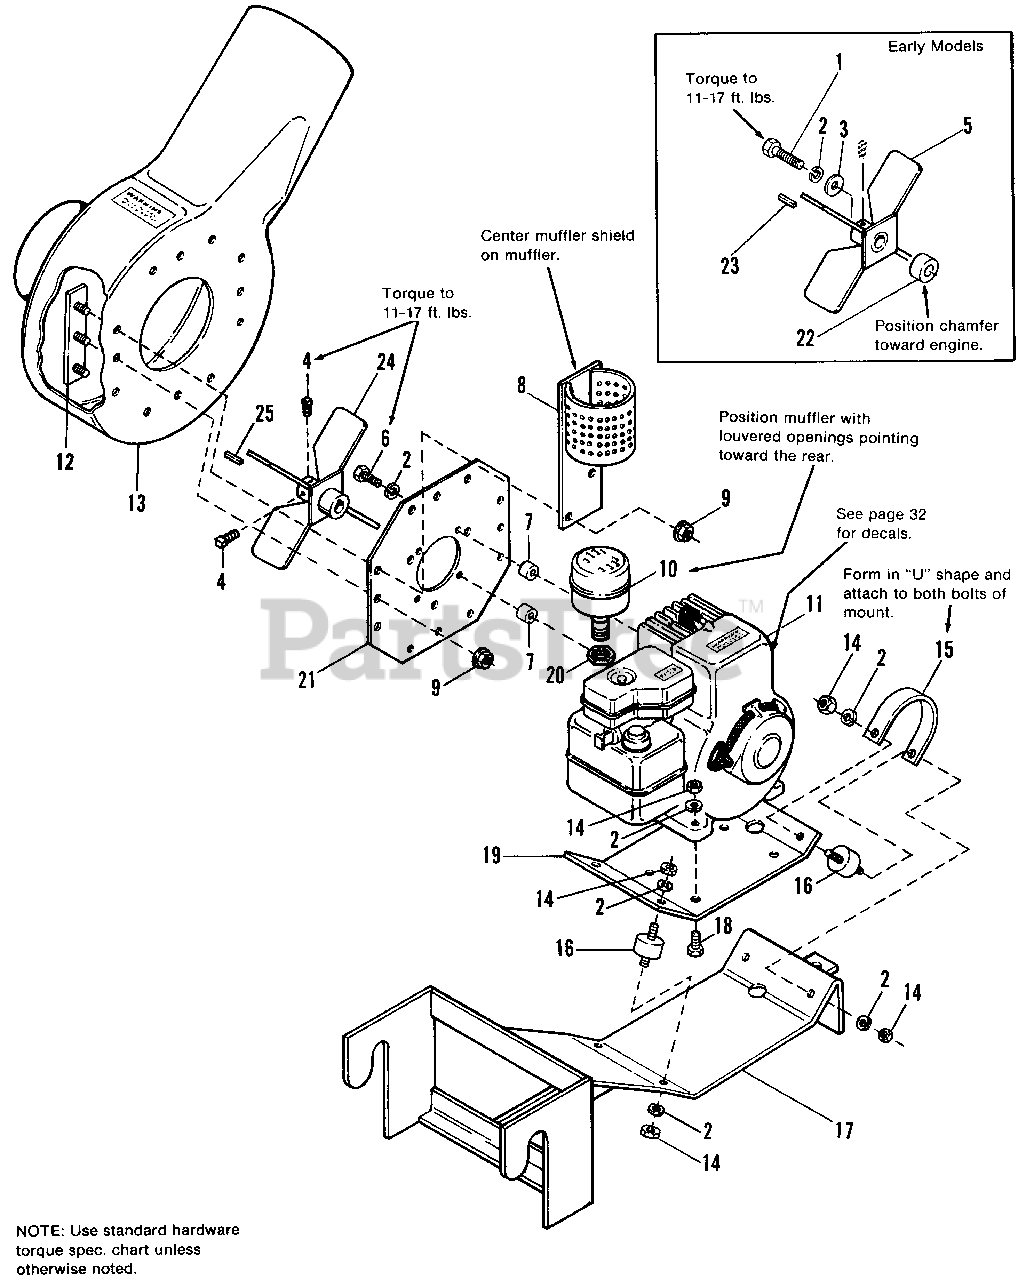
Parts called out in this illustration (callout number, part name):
1	CAPSCREW, Hex Hd., 5/16-24 x 1/2
2	LOCKWASHER, 5/16 (Qty.17 used before s/n 2890)
3	WASHER
4	SETSCREW, 5/16-18 x 1/2
5	FAN ASSY.
6	CAPSCREW, Hex Hd., 5/16-24 x 1-1/4
8	SHIELD ASSY., Muffler
9	LOCKNUT, Hex, Flange, 5/16-18
11	ENGINE, Briggs & Stratton, 4 HP
12	BAR ASSY.
14	NUT, Hex, Full, 5/16-18
15	STRAP, Ground
17	FRAME ASSY.
18	CAPSCREW, Hex Hd., 5/16-18 x 1-1/2
19	PLATE, Engine
20	LOCKNUT, 1/2
21	PLATE, Housing Support
22	SPACER
23	KEY, 3/16 x 3/16 x 1
24	FAN ASSY., 3/16 x 3/16 x 1-7/8 (Incl. Ref. Nos. 4 & 25)
25	KEY
